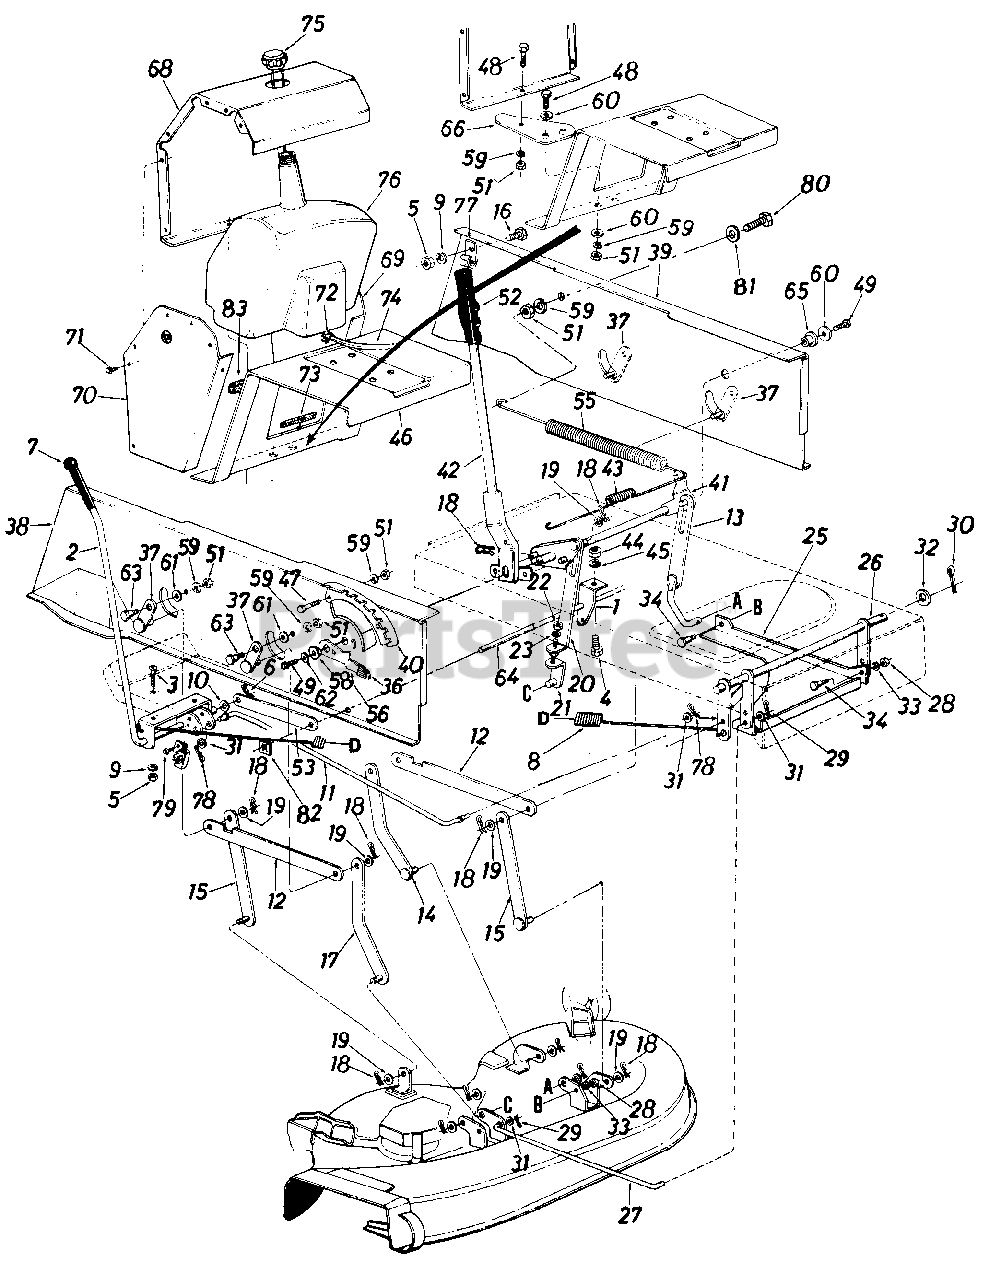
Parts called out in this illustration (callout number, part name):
1	Spring Hanger Bracket
2	Deck Engagement Lever Ass'y.
3	Truss Mach. Scr. 5/16-18 x .75" Lg.
4	Hex Bolt 1/4-20 x .62" Lg.
5	Hex Nut 5/16-18 Thd.*
6	Cotter Pin 3/32" Dia. x 1.00" Lg.
8	Ext. Spring .99" O.D. x 22" Lg.
9	L-Wash. 5/16" I.D.*
10	Fl-Wash. .510" I.D. x 1.0" O.D.
11	Drive Deck Control Rod
12	Connecting Rod 3/16 x 1 x 12.5
13	Deck Lift Link Ass'y.
14	Deck Hanger Link Ass'y.-Rear L.H.
15	Deck Hanger Link Ass'y.
16	Hex Bolt 5/16-18 x .75" Lg.
17	Deck Hanger Link Ass'y.-
18	Inter. Cotter Pin 1/2" Dia.
19	Fl-Wash. .531 I.D. x .93" O.D.
20	Adj. Link Deck Lifting
21	Adj. Lower Link Ass'y.
22	Hex Jam Nut 3/8-24 Thd.
23	L-Wash. 3/8" I.D.
25	Diagonal Brace
26	Stabilizer Shaft Ass'y.
27	Stabilizer Rod
28	Hex Nut 3/8-16 Thd.*
29	Cotter Pin 3/32" Dia. x 1.0" Lg.
30	Cotter Pin 1/8" Dia. x 1.25" Lg.*
31	Fl-Wash. .385" I.D. x .620" O.D.
32	Fl-Wash. .635" I.D. x 1.12" O.D.
33	L-Wash. 3/8" I.D.*
34	Shoulder Bolt 3/8-16
36	Knob-Height Adj.
37	Pivot Link Ass'y.
38	Side Panel Upper Frame-R.H.
39	Side Panel Upper Frame-L.H.
40	Index Brkt.
41	Lift Shaft Ass'y.
42	Lift Handle Brkt. Ass'y.
43	Ext. Spring .56" I.D. x 32 Coils
44	Hex Nut 1/4-20 Thd.
45	L-Wash. 1/4" I.D.
46	Hitch Plate
47	Hex Bolt 5/16-18 x .75" Lg.*
48	Hex Bolt 5/16-18 x 1.00" Lg. (Grade 5)
49	Hex Wash. TT-Tap Scr. 5/16-18 x .62" Lg.
51	Hex Nut 5/16-18 Thd.
52	Grip
53	Link 1.0 x 7.5" x .19
55	Ext. Spring .99" Dia. x 11.00" Lg.
56	Deck Lift-Down Stop
58	Flange Brg. .630" I.D.
59	L-Wash. 5/16" I.D.*
60	Fl-Wash. .344" I.D. x 1.125" O.D. x .125
61	Fl-Wash. .344" I.D. x .62" O.D. x .063
62	Fl-Wash. .344" I.D. x 1.125" O.D.
63	Shld. Bolt .437" Dia. x .180
64	Running Board Rod
65	Flange Brg. .632" I.D.
66	Hitch Bar
68	Gas Tank Housing-Main Panel
69	Side Panel-L.H.-Gas Tank
70	Side Panel-R.H.-Gas Tank
71	Truss Mach. B-Tapp Scr. #10 x .50" Lg.
72	Hose Clamp-.406" Dia.
73	Trim Strip-5" Lg.
74	Gas Line-44" Lg.
75	Gas Tank Cap
76	Gas Tank
77	Hose Clamp
78	Cotter Pin 3/32" Dia. x .75" Lg.
79	Hex Wash. Hd. Tap Scr. 1/4 x .50" Lg.
80	Hex Bolt 5/16-18 x 1.50" Lg.
81	Fl-Wash. .344" I.D. x .875" O.D.
82	Speed Nut for .500" Dia. Stud
83	Foam Strip 3/8" x 1-1/8" x 1-1/2" Lg.
